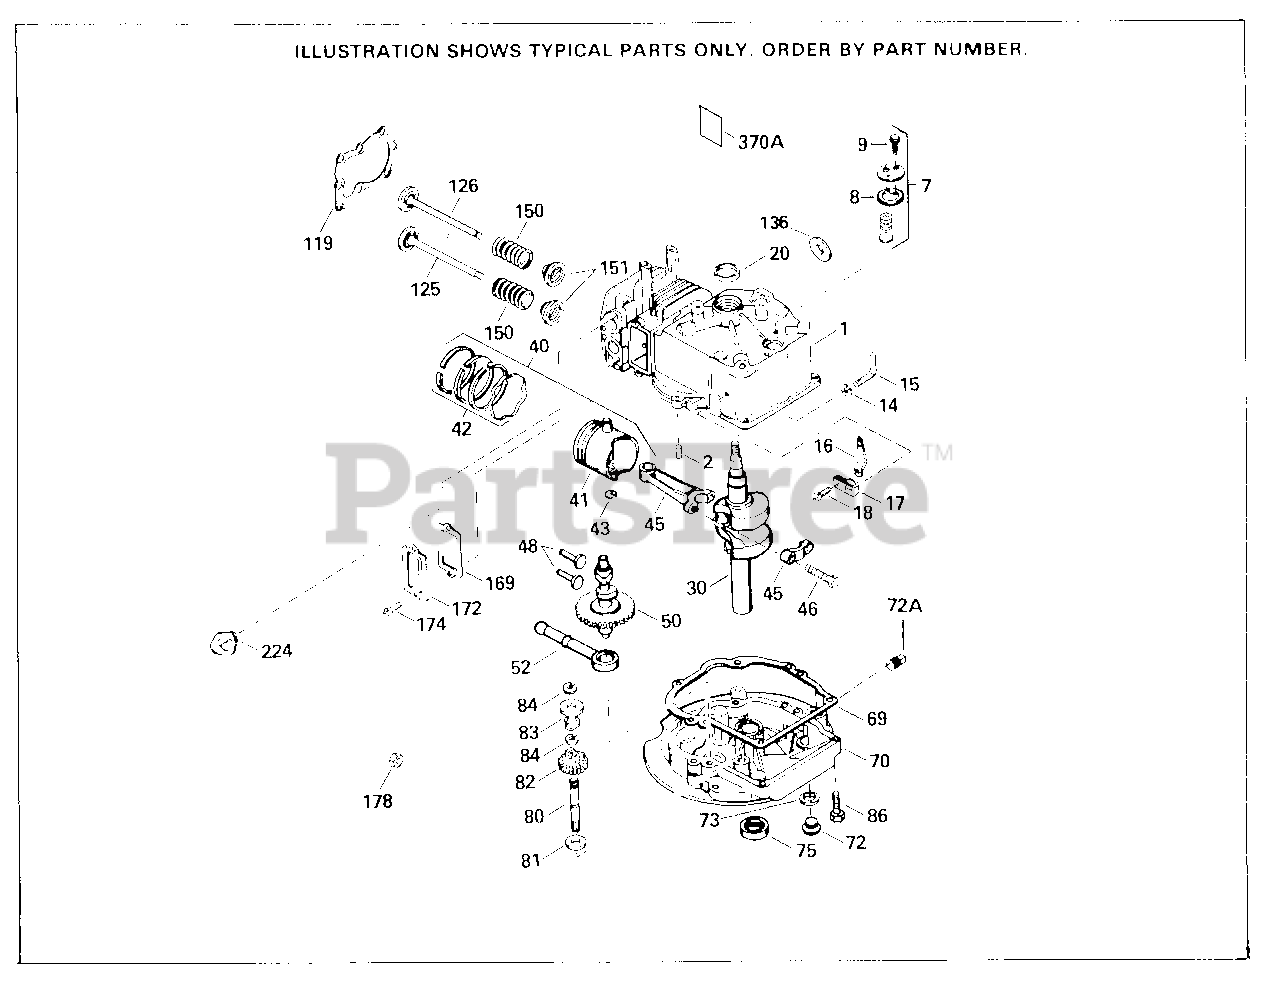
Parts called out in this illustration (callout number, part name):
1	"Cylinder (Incl. 2,7,8,9,20 & 136) 2-5 /8" Bore
2	Dowel Pin
7	Breather Ass'y. (Incl. 8 & 9)
8	Breather Gasket
9	Screw, 10-24 x 9/16"
14	Flat Washer
15	Governor Rod (Incl. 14)
16	Governor Lever
17	Governor Lever Clamp
18	Screw, 8-32 x 5/16"
20	Oil Seal
30	Crankshaft
40	Piston, Pin & Ring Set (Std.) 2-5/8"B ore
40	Piston, Pin & Ring Set (.010" OS)
40	Piston, Pin & Ring Set (.020" OS) (In cl. 41, 42 & 43)
41	Piston & Pin Assembly (Std.) (Incl. 4 3)-5/8")
41	Piston & Pin Assembly (.010" OS) (Inc l. 43)
41	Piston & Pin Assembly (.020" OS) (Inc l. 43)
42	Ring Set (Std.) (2-5/8" Bore)
42	Ring Set (.010" OS)
42	Ring Set (.020" OS)
43	Piston Pin Retaining Ring
45	Connecting Rod Ass'y. (Incl. 46)
46	Connecting Rod Bolt
48	Valve Lifter
50	Camshaft (MCR)
52	Oil Pump Ass'y.
69	Mounting Flange Gasket
70	Mounting Flange Incl. 72, 72A, 73, 75 & 80
72	Oil Drain Plug
72A	Oil Drain Plug
73	Drain Plug Gasket
75	Oil Seal
80	Governor Shaft
82	Governor Gear Ass'y. (Incl. 81)
83	Governor Spool
84	Retaining Ring
86	Screw, 1/4-20 x 1-1/4"
119	Cylinder Head Gasket
125	Exhaust Valve (Std.) (Incl. 151)
125	Exhaust Valve (1/32" OS) (Incl. 151)
126	Intake Valve (Std.) (Incl. 151)
126	Exhaust Valve (1/32" OS) (Incl. 151)
136	SE Brake Bracket Washer
150	Valve Spring
151	Valve Spring Keeper
169	Valve Cover Gasket
172	Valve Cover
174	Screw, 10-24 x 1/2"
178	Nut, Carburetor bowl
224	Intake Pipe Gasket
370A	Decal, Instruction
